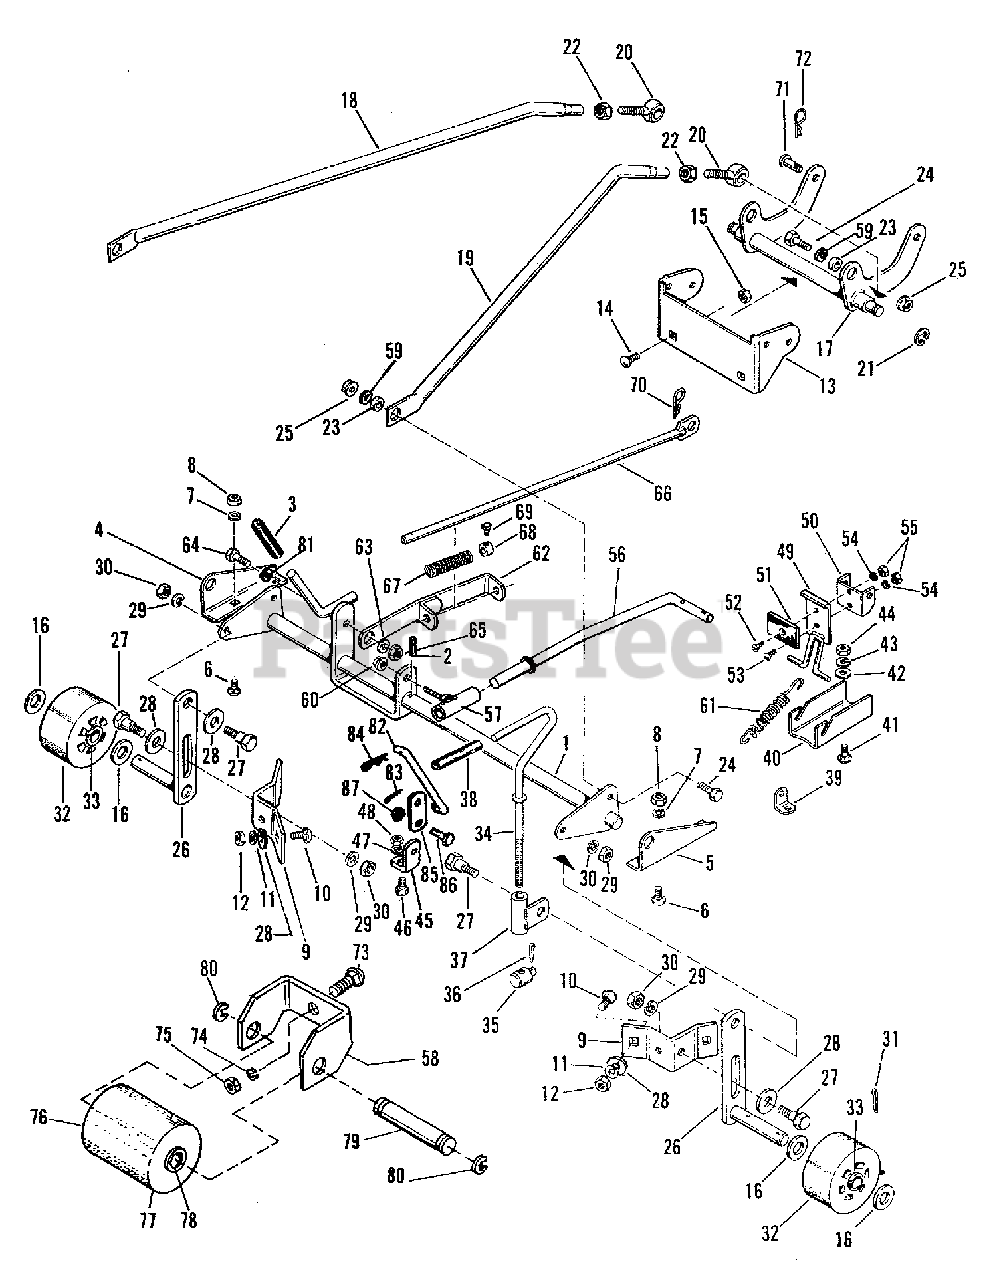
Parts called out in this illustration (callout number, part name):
1	CONTROL ARM ASSEMBLY
2	PIN, Roll, 1/8 x 1
3	GRIP, Handle
4	BRACKET, L.H., Pivot
5	BRACKET, R.H., Pivot
6	BOLT, Carriage, 5/16-18 x 5/8 Lg.
7	LOCKWASHER, 5/16
8	NUT, Full Hex, 5/16-18
9	SUPPORT, Roller Brake
10	BOLT, Carriage
11	LOCKWASHER, 5/16
12	NUT, Full Hex, 5/16-18
13	BRACKET, Forward Mower
14	SCREW, Whiz Lock, 5/16-18 x 3/4
15	NUT, Flange, 5/16-18
17	ROCKER ARM ASSEMBLY
18	ARM, L.H. Adjusting
19	ARM, R.H., Adjusting
21	RING, Retaining
22	NUT, Hex Jam, 1/2-20
24	CAPSCREW, Hex, 3/8-16 x 1 Lg.
25	LOCKNUT, 3/8-16
26	ROLLER SUPPORT ASSEMBLY
27	BOLT, Shoulder, 3/8-16 X 1.34
28	WASHER, Plain, 7/16
29	LOCKWASHER, 3/8
30	NUT, Full Hex, 3/8-16
31	PIN, Cotter, 3/16 x 1
32	ROLLER ASSEMBLY
36	PIN, Cotter, 3/32 x 1
37	ROD GUIDE ASSEMBLY
39	ANCHOR, Spring
40	BRACKET, Pivot
41	BOLT, Carriage
42	WASHER, Plain, 5/16
43	LOCKWASHER, 5/16
44	NUT, Full Hex, 5/16-18
46	CAPSCREW, Hex, 5/16-18 x 5/8 Lg.
47	LOCKWASHER, 5/16
48	NUT, Full Hex, 5/16-18
49	BRAKE SUPPORT ASSEMBLY
50	ANCHOR, Brake Rod
51	SHEAVE, Brake
52	SCREW, Flat Head, Machine No. 10-24 x 5/8 Lg.
53	SCREW, Flat Head, Machine No. 10-24 x 1/2 Lg.
54	LOCKWASHER, No. 10
55	NUT, Hex, No 10-24
56	ROD, Brake
57	ROD GUIDE ASSEMBLY
58	BRACKET, Control Roller
59	WASHER, Flat, 3/8
60	LOCKNUT, 3/8-16
62	ROD GUIDE ASSEMBLY
64	CAPSCREW, Hex, 3/8-16 x 1 Lg.
65	LOCKNUT, 3/8-16
66	CLUTCH ROD ASSEMBLY
68	COLLAR, Set
69	SCREW, Set, 1/4-20 x 3/8 Lg.
70	CLIP, Hairpin
72	CLIP, Spring
73	BOLT, Carriage, 5/16-18 x 5/8
74	LOCKWASHER, 5/16
75	NUT, Hex, 5/16-18
76	ROLLER ASSEMBLY
79	SHAFT, Control Roller
80	RING, "E"
81	WASHER, Flat, 3/8
83	PIN, Cotter, 3/32 x 5/8
84	CLIP, Hairpin
86	CAPSCREW, 5/16-18 X 3/4
87	LOCKNUT, 5/16-18
